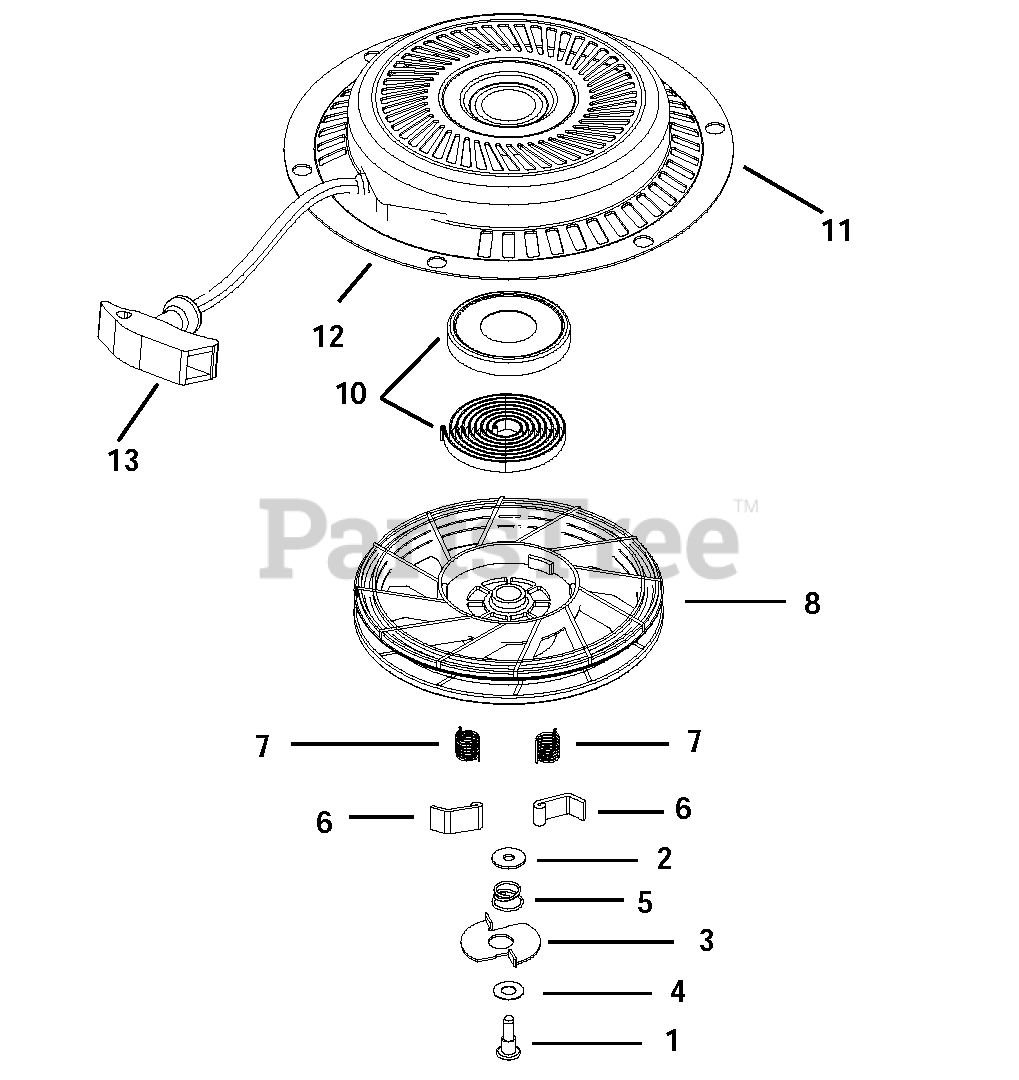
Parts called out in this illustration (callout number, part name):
1	Center Screw
3	Retainer
5	Brake Spring
6	Starter Dog
7	Dog Spring
10	Spring & Keeper
11	Starter Housing Assembly
12	Starter Rope Length 69.5" x 11/64" di a.
13	Starter Handle
